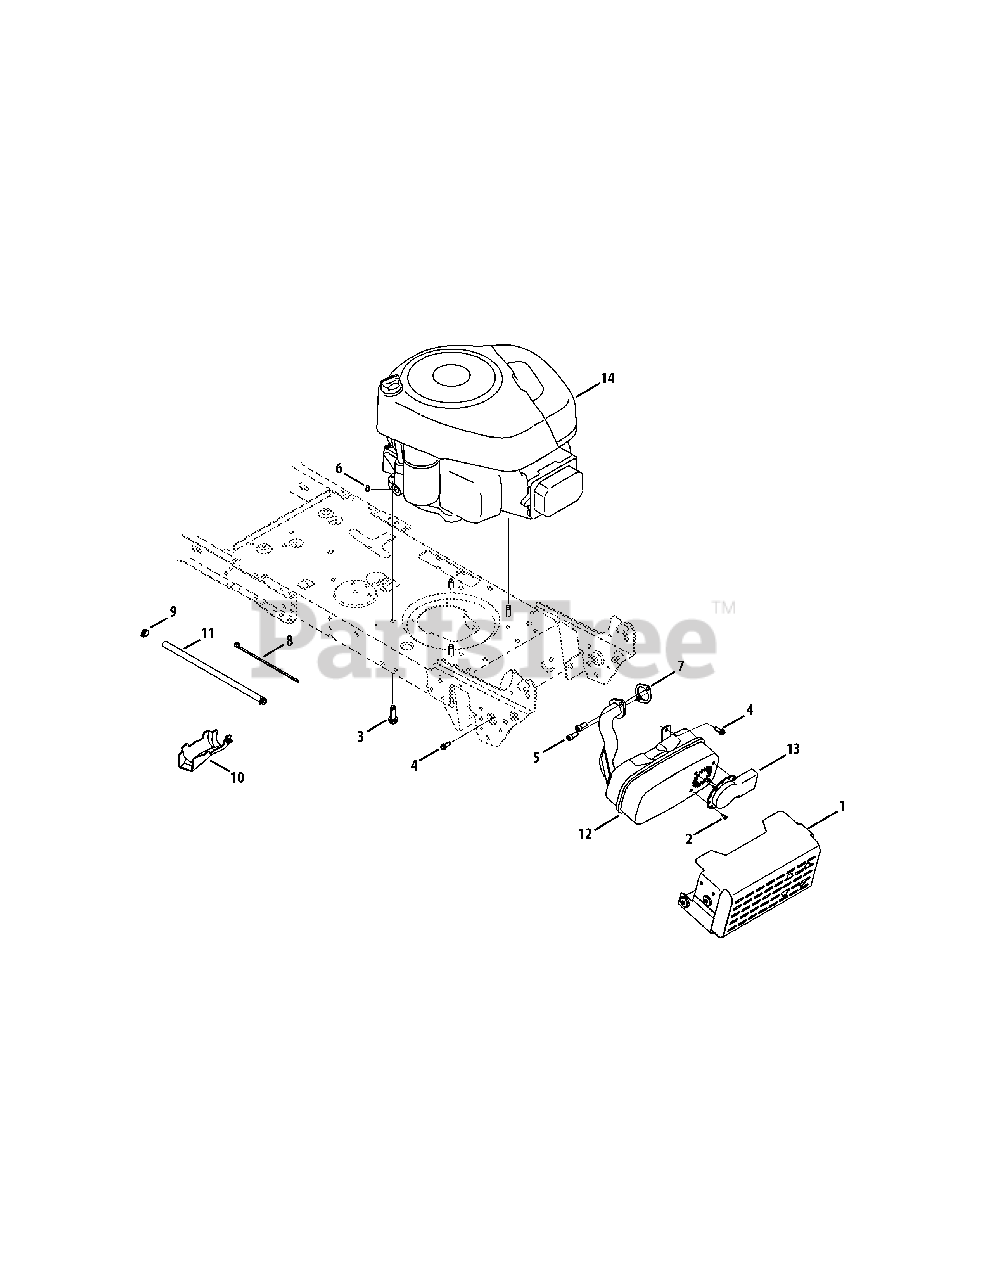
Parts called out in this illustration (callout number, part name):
1	Muffler Shield Assembly
2	Screw, AB #8-18 0.500
3	Tap Screw, 3/8-16 1.000
4	Tap Screw, 1/4-20 0.750
5	Screw, Socket Head, 5/16-18 x .750
6	Sems Nut, 1/4-20
7	Exhaust Gasket
8	Cable Tie, 3/16 X .05 X 7.4
9	Hose Clamp, .490 Dia.
10	Oil Drain Sleeve
11	Low Permeation Fuel Hose, 1/4
12	Briggs Single Muffler
13	Long Muffler Deflector
14	Engine - 331877-0869-G5
